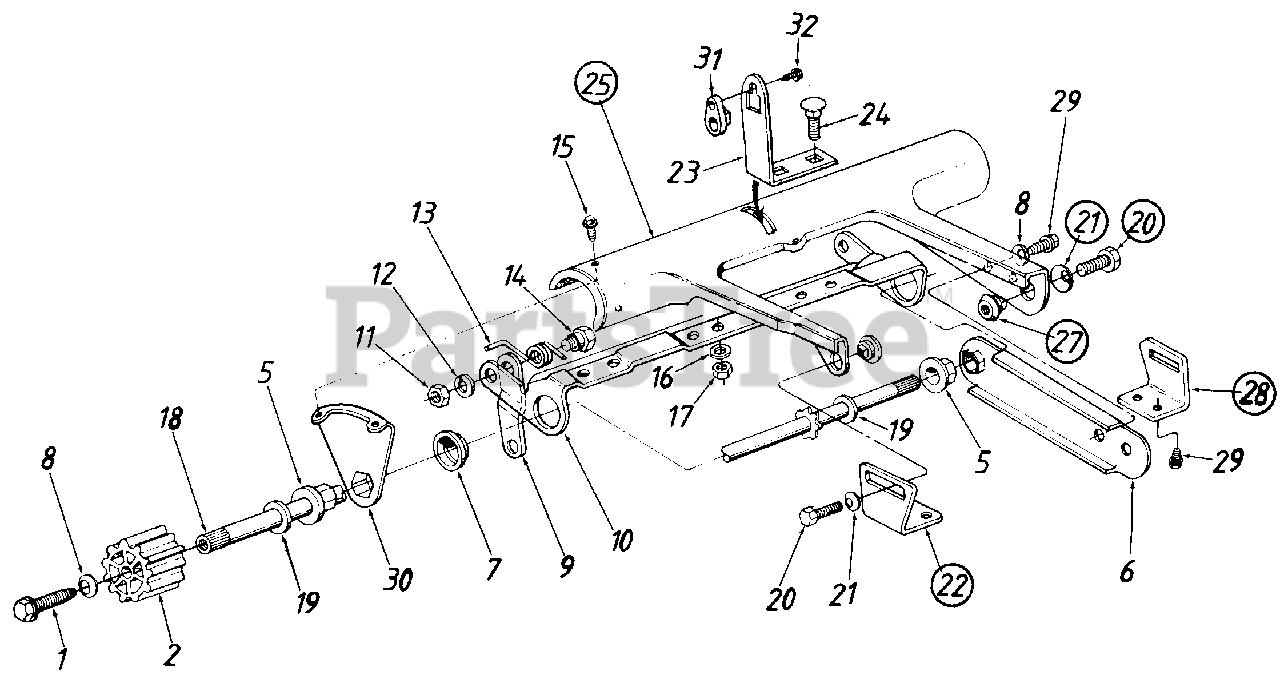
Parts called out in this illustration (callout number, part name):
1	Hex Wash. Hd. Tap Scr. 1/4-20 x .75" Lg.
2	Wheel Drive Pinion-Half
5	Hex Flange Brg. .504" I.D.
8	Bell-Wash. .265" I.D. x .75" O.D.
11	Hex Nut 5/16-18 Thd.
12	L-Wash. 5/16" I.D.
13	Torsion Spring-R.H.
14	Shoulder Bolt .437" Dia.
15	Hex L-Hd. AB-Tap Scr. 1/4" x .62" Lg.
16	L-Wash. 1/4" I.D.
17	Hex Nut 1/4-20 Thd.
18	Drive Shaft Ass'y.
19	Fl-Wash. .531" I.D. x .93" O.D.
20	Hex Bolt 5/16-18 x 5/8" Lg.
21	Bell-Wash. .345" I.D. x .88" O.D.
22	Pivot Bracket - R.H.
28	Pivot Bracket - L.H.
29	Hex Wash. Hd. AB-Tap Scr. 1/4 x.62" Lg.
32	Hex B-Tap Scr. #10 x .44" Lg.
